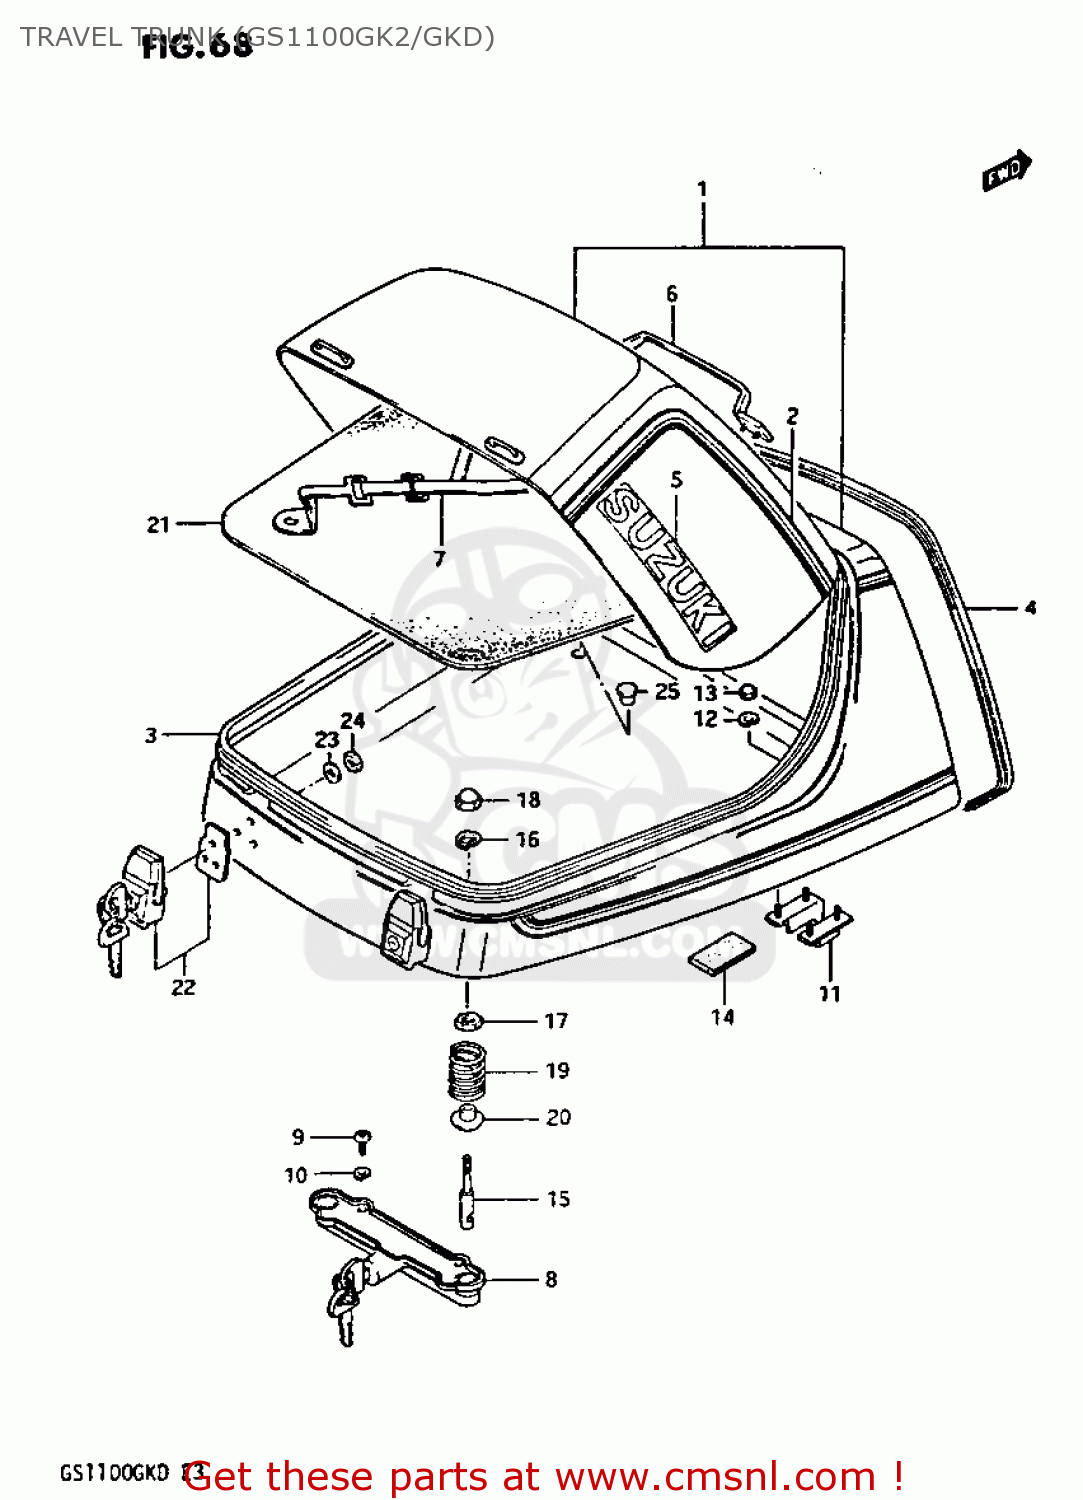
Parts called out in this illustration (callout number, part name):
1	TRAVEL TRUNK (BROWN/BROWN)
2	TAPE SET,COWLING BODY
3	SEAL,TRAVEL TRUNK
4	MOLDING,TRAVEL TRUNK
5	EMBLEM,COWLING
6	GRIP TRAVEL TRUNK
7	BAND SET
8	LOCK,TRAVEL TRANK
9	SCREW 6X12
10	WASHER,LOCK
11	HOOK COMP TRAV TRUNK
12	LOCK WASHER
13	NUT
14	CUSHION TRAVEL TRUNK
15	LOCK BOSS TRAV TRUNK
16	WASHER,LOCK
17	NUT
18	NUT
19	SPRING,TRAVEL TRUNK
20	GUIDE,TRAVEL TRUNK SPRING
21	CUSHION TRAVEL TRUNK
22	LOCK,TRANK LID
23	WASHER 4MM
24	NUT 4MM
25	PLUG(OD:14)
